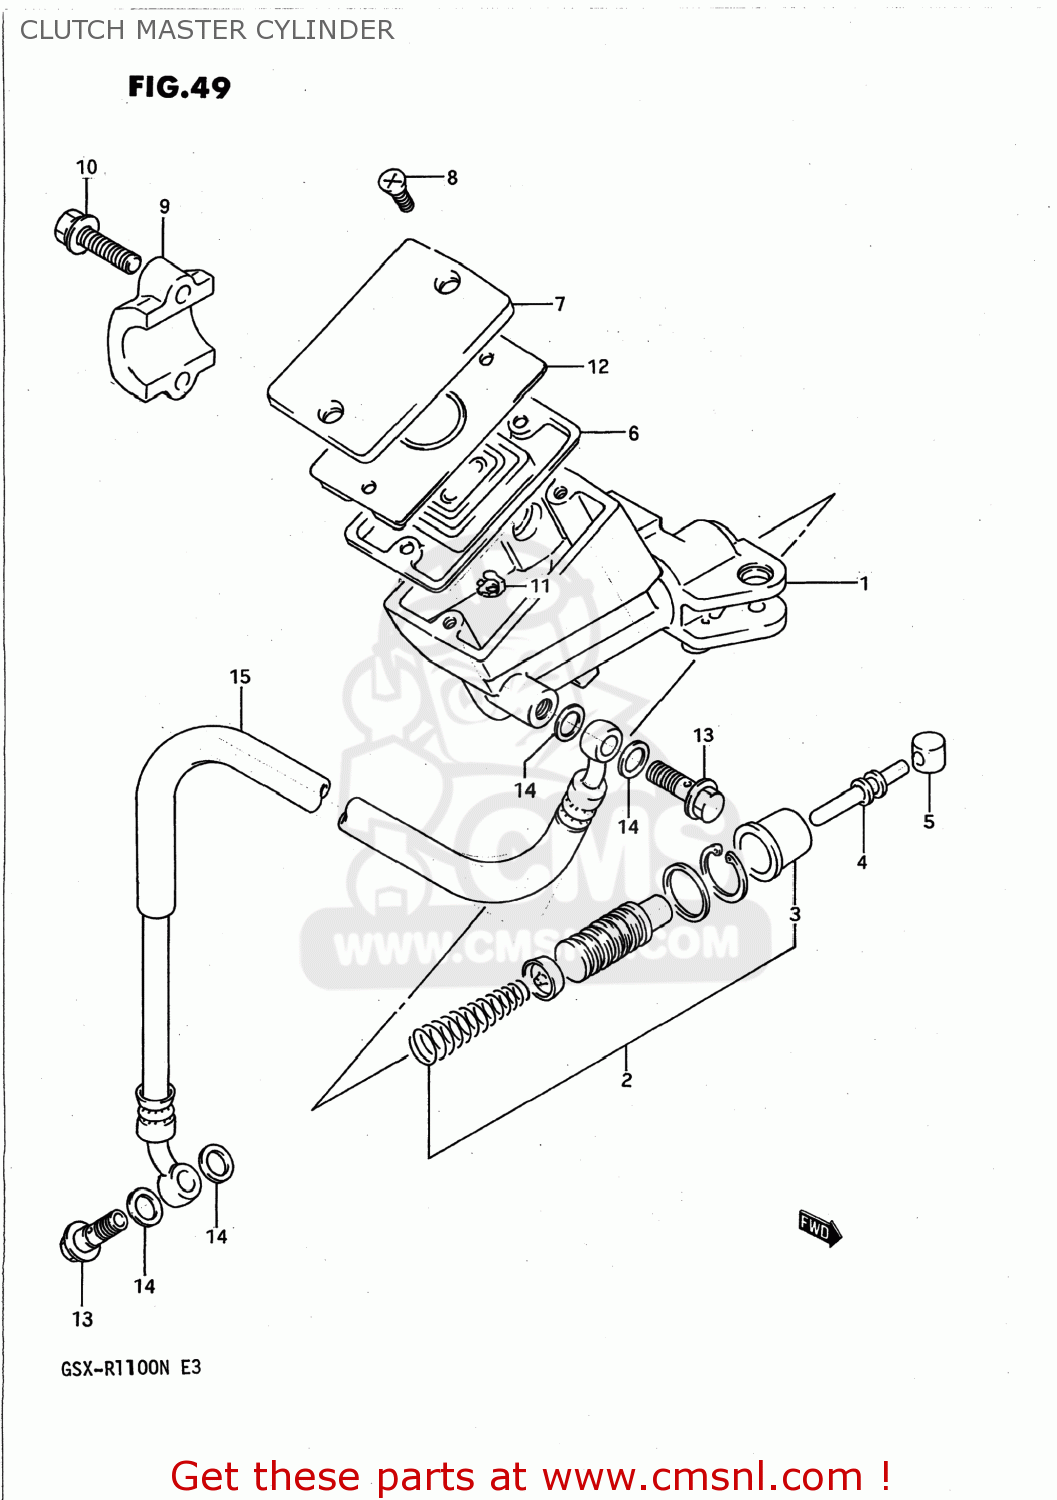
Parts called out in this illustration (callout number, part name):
1	CYLINDER ASSEMBLY,CLUTCH MASTER
2	PISTON & CUP SET
3	BOOT
4	ROD,PUSH
5	BUSH
6	7
7	CAP
8	SCREW
9	HOLDER
10	BOLT
11	PROTECTOR
12	PLATE,DIAPHRAGM
13	BOLT UNION
14	WASHER(10X15X1.5)
15	HOSE COMP,CLUTCH
